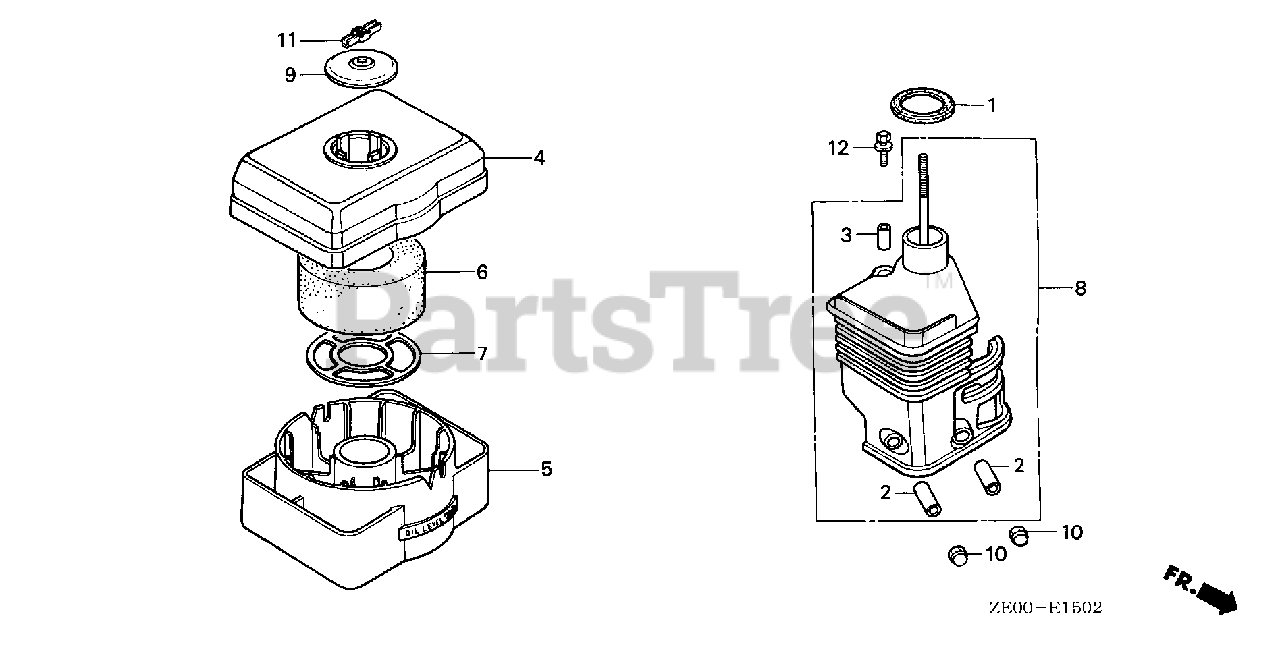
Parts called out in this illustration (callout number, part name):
1	GASKET, ELBOW
2	COLLAR, AIR CLEANER (NOT AVAILABLE)
2	COLLAR, AIR CLEANER
3	COLLAR B, AIR CLEANER
4	BODY, CLEANER (OIL BATH)
5	PAN, CLEANER OIL (OIL BATH)
6	ELEMENT, AIR CLEANER (OIL BATH)
7	GRID, AIR CLEANER
8	ELBOW, AIR CLEANER
9	CAP, CLEANER
10	NUT, CAP (6MM)
11	NUT, AIR CLEANER COVER (DACRO COATING)
12	BOLT-WASHER (6X20)
